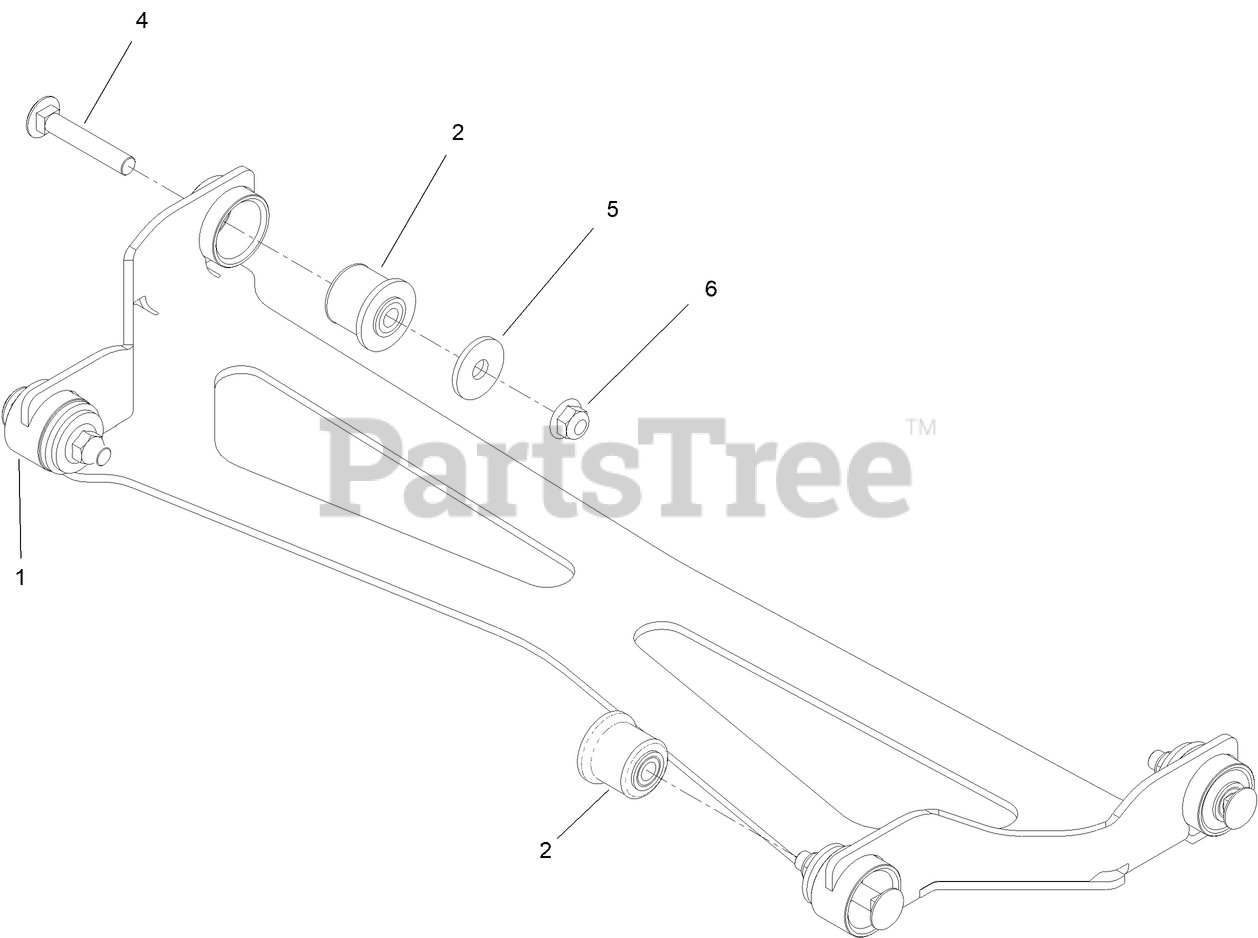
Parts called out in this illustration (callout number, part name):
1	ASM-DECK STRUT [BLACK]
2	SPACER, BUSHING ASM
4	SCREW-CARR
5	WASHER
6	NUT-HF, NI
